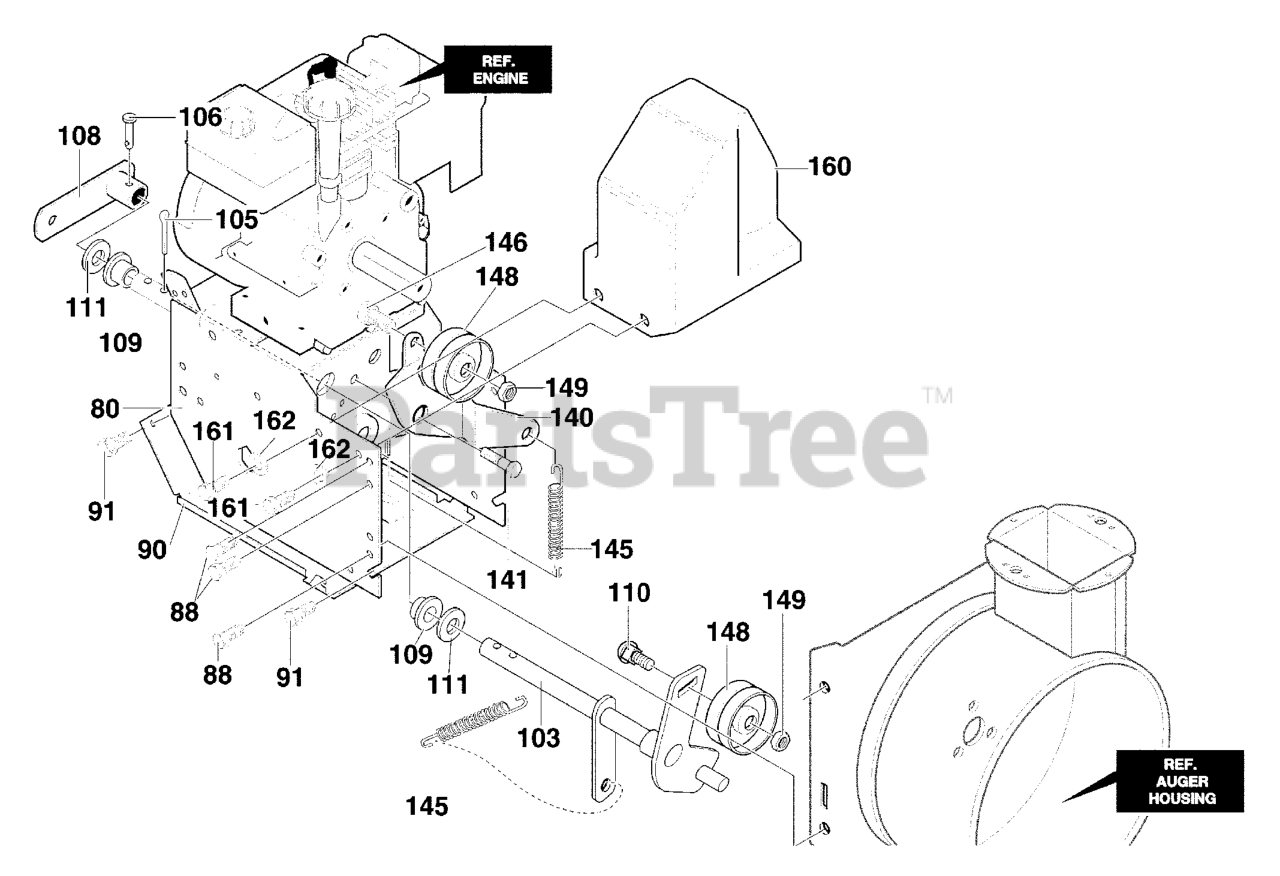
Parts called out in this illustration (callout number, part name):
80	FRAME ASSY
88	SCREW, 5/16-18 x 0.50
90	COVER, BOTTOM
91	SCREW, 1/4-20X .63
103	IDLER ASSEMBLY
105	PIN, HAIR .38DIAX1.64LG
106	PIN, KLIK 3/16" DIA
108	ASSY., SPRING ATTACH WHEEL
109	BEARING, FL.
110	BOLT, 3/8-16X1.25 CARR.
111	WASHER, FLAT
140	LEVER, IDLER ARM TRACTION
141	BOLT, .625X.135 HHSH 5/16-18
145	IDLER SPRING TRACTION DRIVE
146	SCREW, 3/8-16 x 1.25
148	PULLEY, IDLER
149	NUT, 3/8-16
160	COVER, BELT
161	SCREW, 1/4-20X .63
162	WASHER, FLAT
